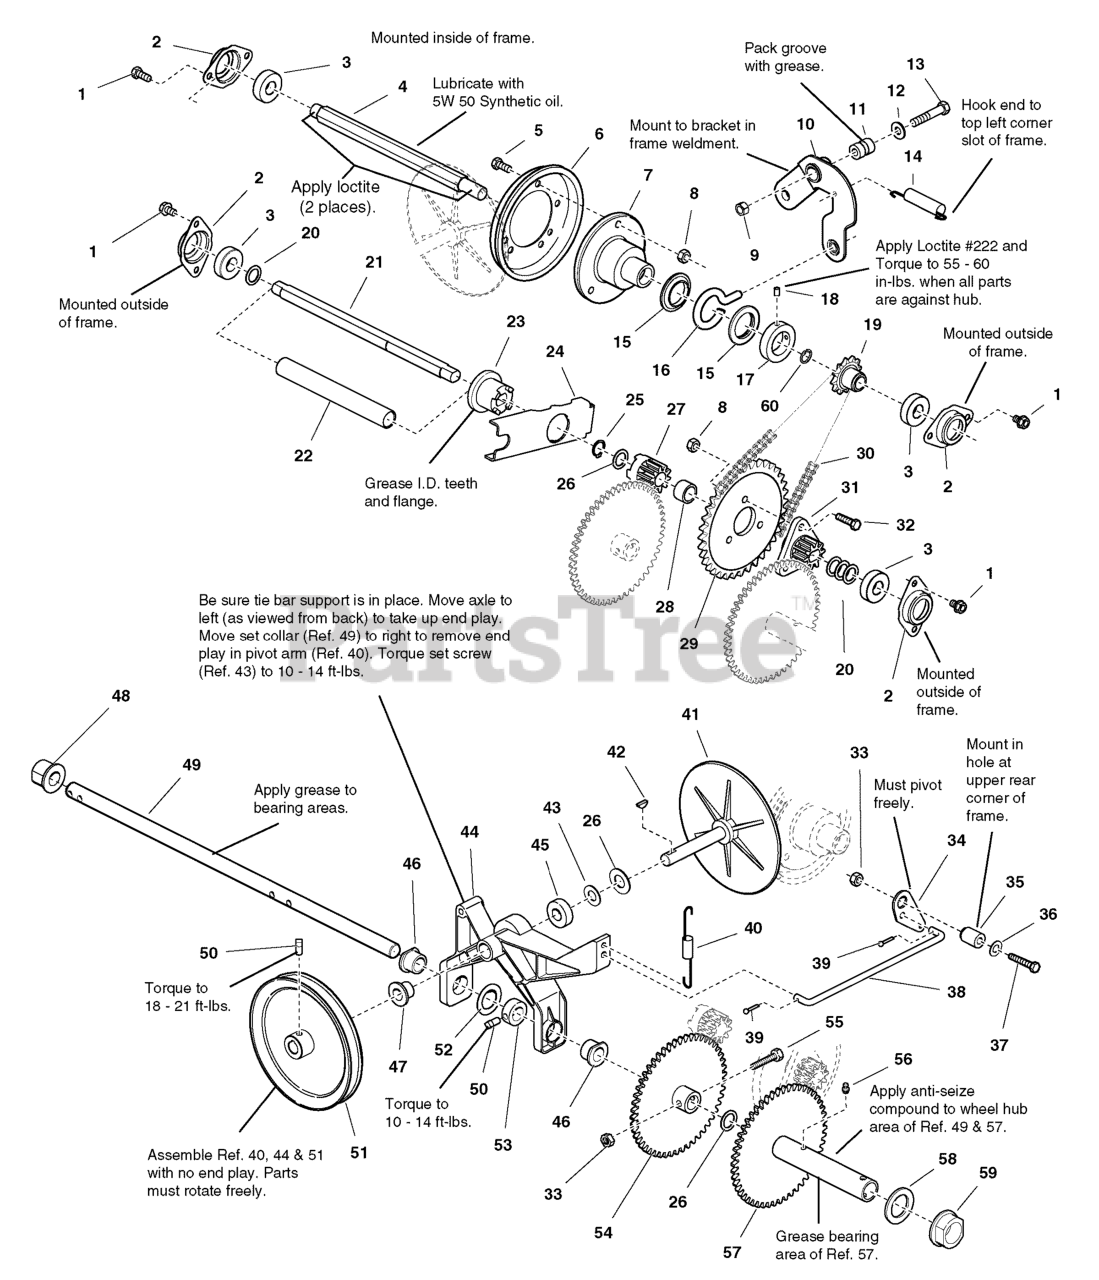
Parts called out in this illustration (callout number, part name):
1	SCREW, Hex Washer Head Taptite, 5/16-18 x 5/8
2	RETAINER, Bearing
3	BEARING, Ball
4	SHAFT, Hex
5	CAPSCREW, Hex Head, 5/16-18 x 3/4, G5
6	DISC, Friction with Insert
7	HUB, Friction Disc
8	NUT, Hex Keps Conical Washer, 5/16-18
9	NUT, Hex Flange, 3/8-16 ESNA
10	ARM ASSEMBLY, Shift with Bushing
11	BUSHING, 19/50 ID x 3/4 OD x 1-3/100 LG
12	WASHER, 3/8
13	CAPSCREW, Hex Head, 3/8-16 x 2, G5
14	SPRING, Extension
15	COLLAR, Thrust
16	PIN, Loop
17	COLLAR, Set
18	SCREW, Set Square Head Cup Point, 1/4-20 x 1/2
19	SPROCKET, 10 T
20	WASHER, 5/8
21	JACKSHAFT, Double D
22	SPRING, Complete
23	CLUTCH, Sliding, 1/5 LG, Powdered Metal
24	ARM, Clutch
25	RING, Retaining Extension
26	WASHER, 3/4
27	GEAR, Stationary Clutch
28	SPACER, Heat Treated, 31/100 LG
29	SPROCKET
30	CHAIN, Roller
31	GEAR, Double D
32	CAPSCREW, Hex Head, 5/16-18 x 1, G5
33	NUT, Hex Flange, 5/16-18 ESNA
34	BELLCRANK
35	BUSHING, 11/32 ID x 3/4 OD x 1-3/50 LG
36	WASHER, 11/32 x 3/4 x 1/16
37	CAPSCREW, Hex Head, 5/16-18 x 1-3/4, G5
38	ROD, Pivot, 9-15/100 LG
39	PIN, Quick
40	SPRING, Extension
41	DRIVE DISC with SPINDLE
42	KEY, Woodruff, 47/250 x 5/8
43	WASHER, 5/8
44	ARM, Pivot with Bushings & Bearings
45	BEARING, Ball
46	BUSHING, 3/4 ID x 1 OD x 3/4 LG, Powdered Metal
47	BUSHING, 5/8 ID x 13/16 OD x 3/4 LG, Powdered Metal
48	BUSHING, 377/100 ID x 1-13/100 OD x 1 LG, Powdered Metal
49	AXLE, Round
50	SCREW, Set Square Head Cup Point, 5/16-18 x 1/2 G8
51	PULLEY & HUB ASSEMBLY
52	WASHER
53	COLLAR, Set
54	GEAR & HUB ASSEMBLY, R.H.
55	CAPSCREW, Hex Head, 5/16-18 x 1-1/2, G8
56	FITTING, Lube, 1/4-28, Tappered with Check Ball
57	GEAR & HUB ASSEMBLY, with Bushings
58	WASHER, 1-47/250
59	BUSHING, 1-27/200 ID x 1-157/250 OD x 3/4 LG
60	RING, Retaining External, #87
